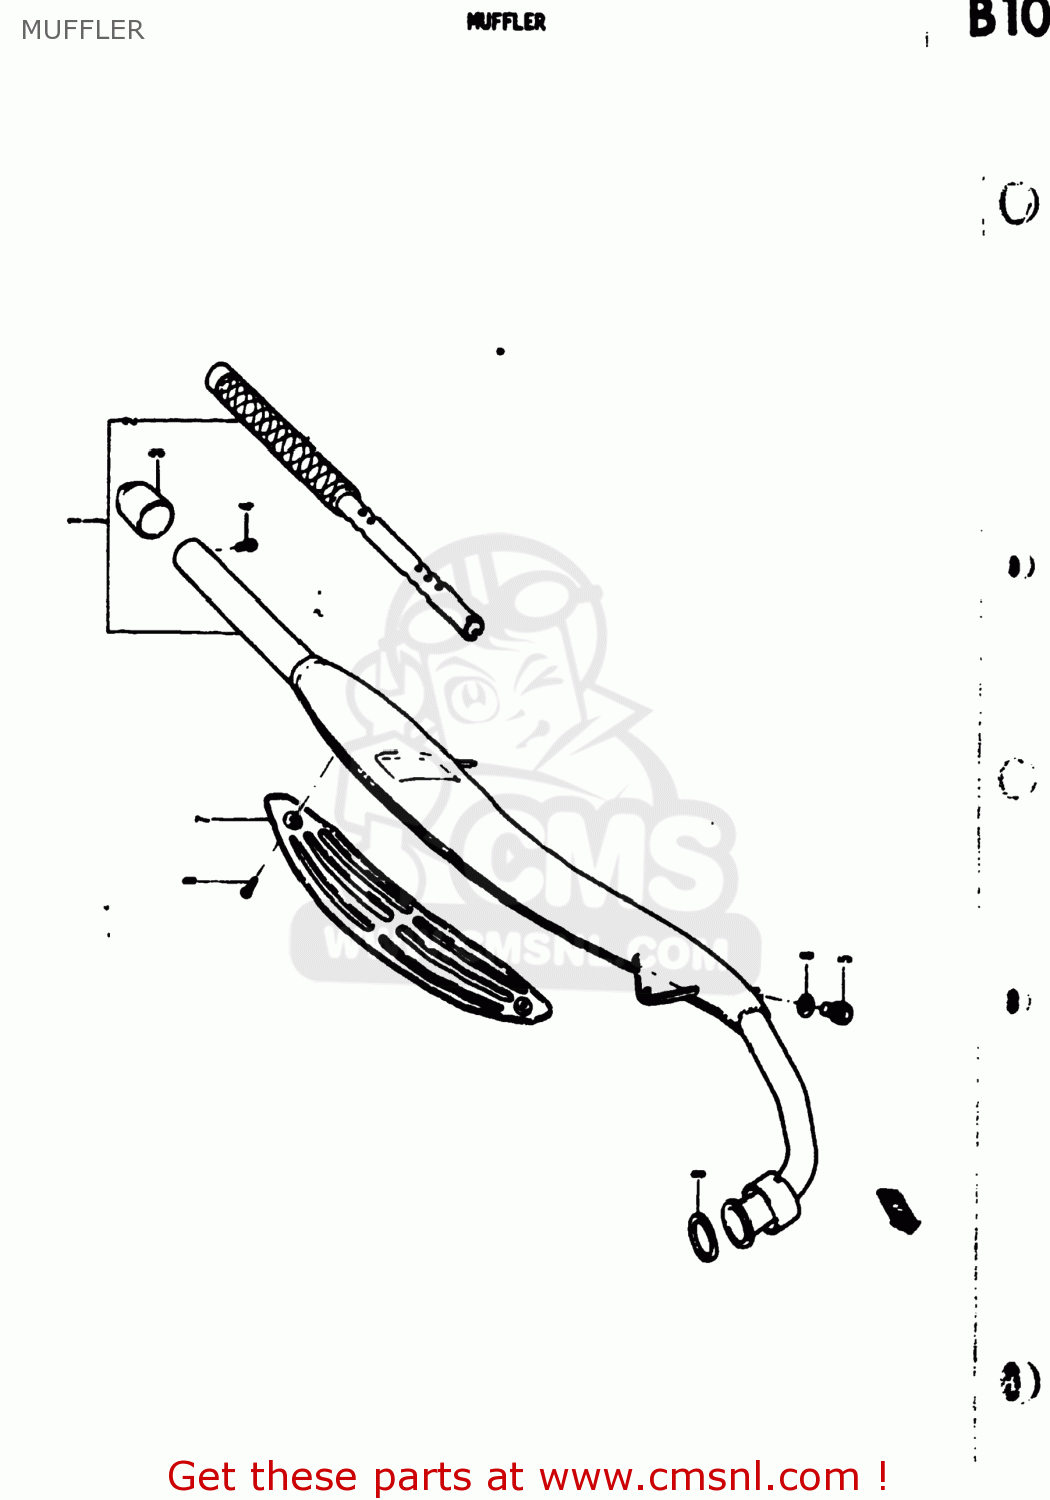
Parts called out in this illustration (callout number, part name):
1	MUFFLER ASSEMBLY
2	PIPE,BAFFLE
3	CUTTER, MUFFLER
4	SCREW
5	BOLT 10X9
6	GASKET(10X14X3.6) (NAS)
7	COVER,MUFFLER
8	SCREW,6X6
9	GASKET,EXHAUST PIPE (NAS)
